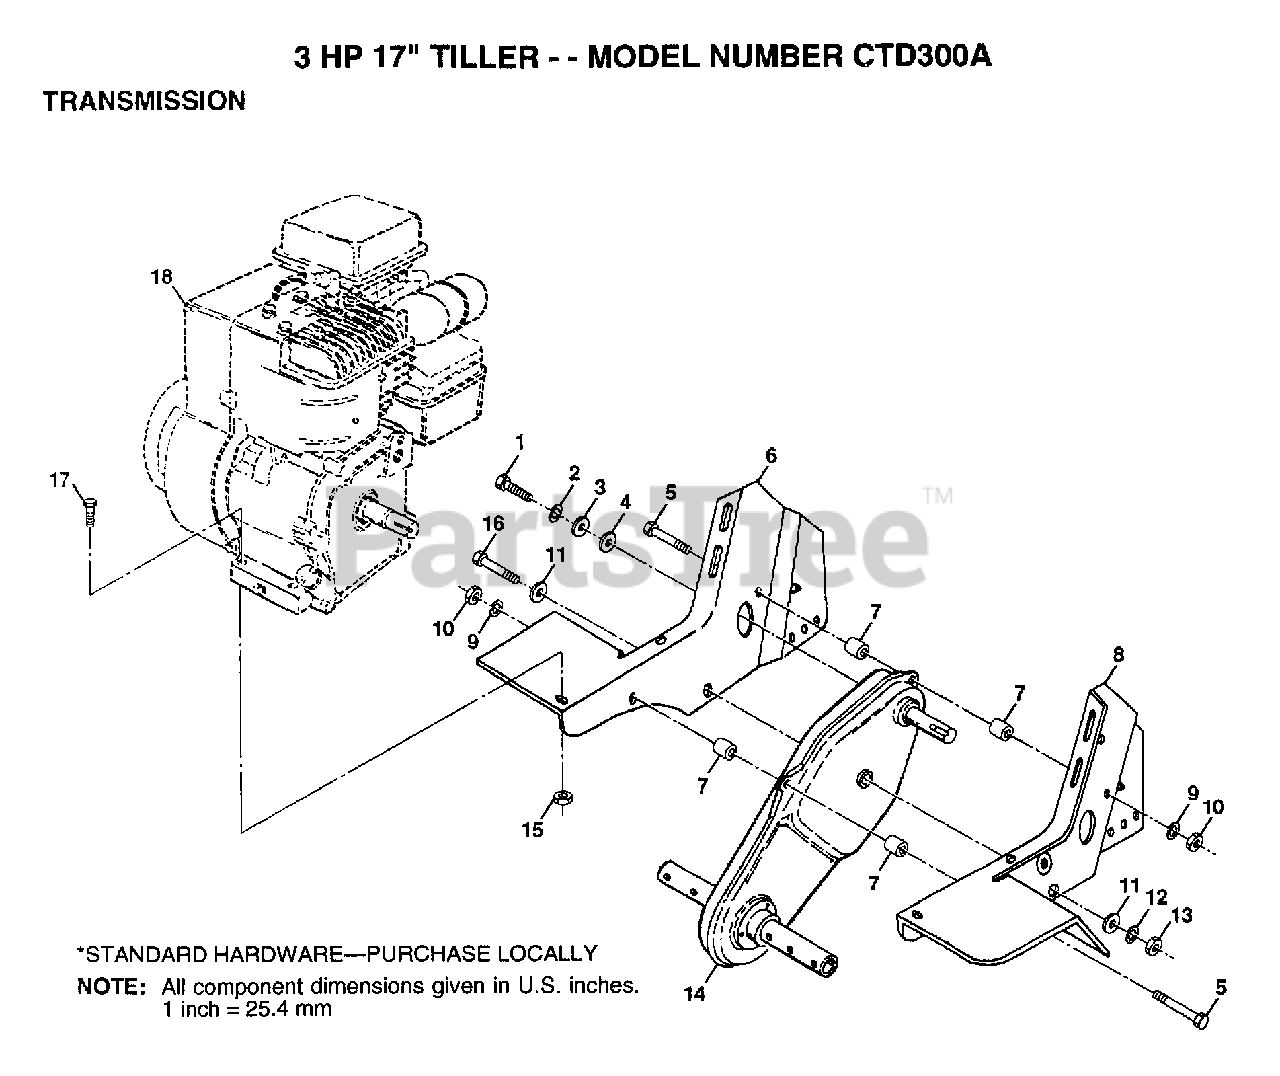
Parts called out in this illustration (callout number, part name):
1	BOLT
2	LOCKWASHER
3	WASHER
4	WASHER
6	"BRKT,ENG RH"
7	SPLIT SPACER RT
8	ENGINE BRKT LH
9	LOCKWASHER
10	NUT.HEX.5/16-18
11	WASHER
12	LOCKWASHER
13	GRIPCO NUT
16	BOLT.3/8-24X3.75
17	BOLT.HEX.5/16-1.5
